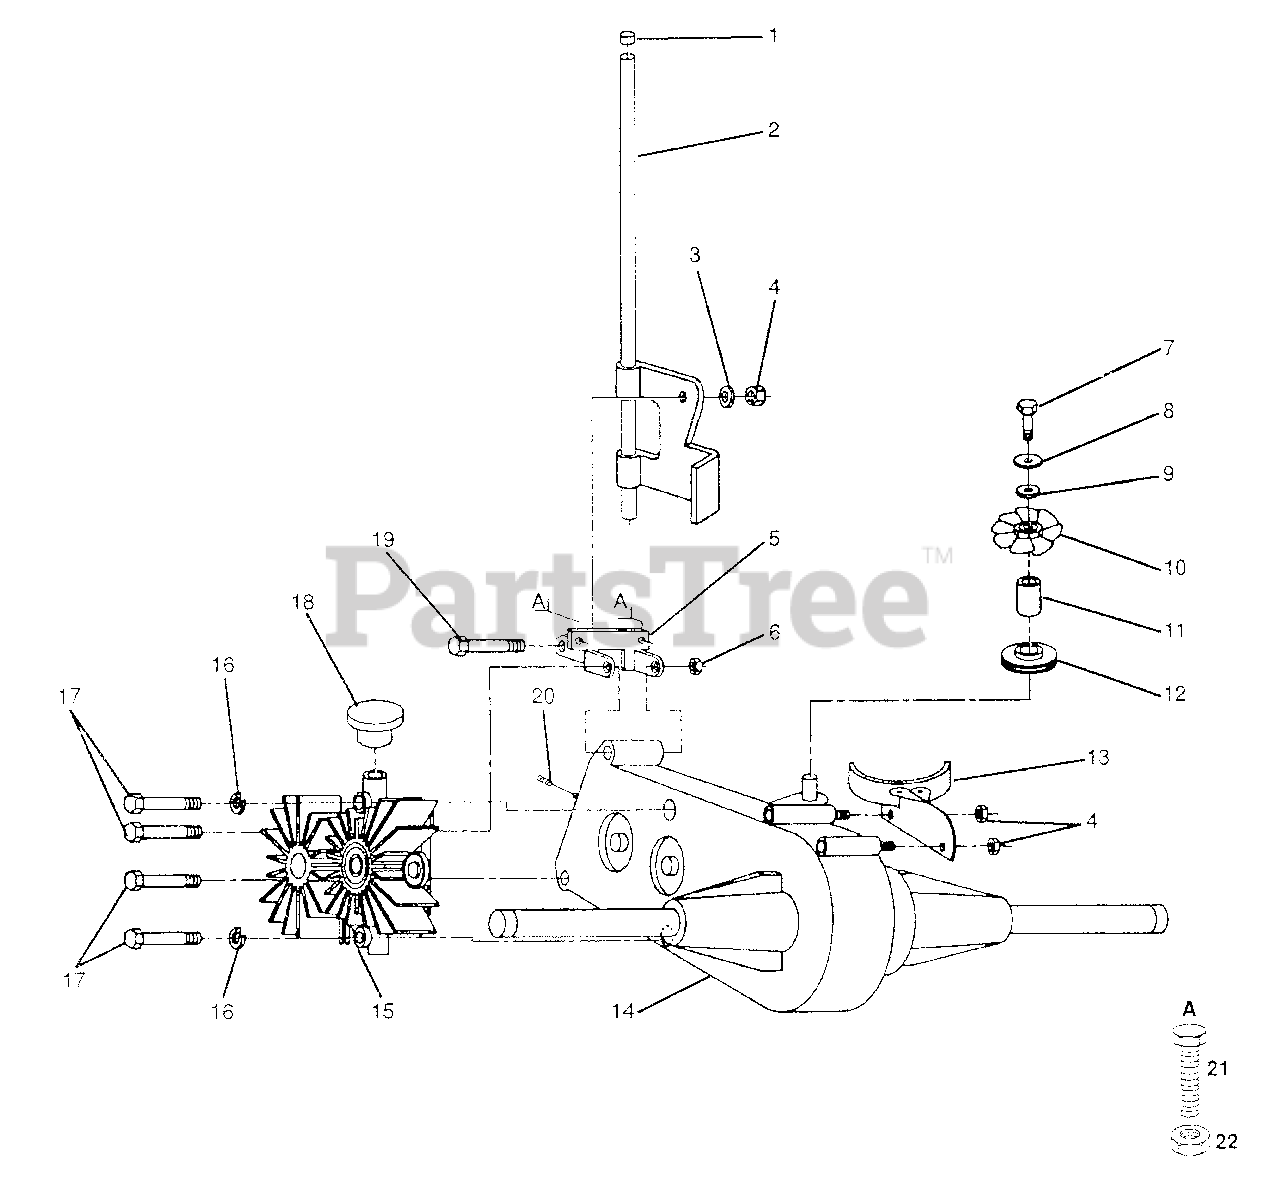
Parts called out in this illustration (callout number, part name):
1	Cap, Plunger
2	Rod, Free Wheel Control Assembly
3	Washer, Nylon
4	Nut, Crownlock 1/4 - 20 UNC
5	Bracket, Mounting Differential
6	Nut, Crownlock 5/16 - 18
7	Bolt, Hex 1/4 - 20 UNC x 3/4
8	Washer, Lock
9	Washer 9/32 x 1-1 /4 x 16 Gauge
10	Fan, Hydro 8"
11	Standoff, Fan, Hydro
12	Pulley, Transaxle
13	Guard Assembly, Belt
14	Differential Assembly
15	Pump Assembly
16	Washer, Lock
17	Bolt, Hex, Fin 5/16 - 18 UNC x 4.5
18	Reservoir, Pump
19	Bolt, Shoulder 1/4 - 20 UNC
20	Spring, Compression
21	Bolt 3/8 - 16 x 3/4
22	Nut, Crownlock 3/8 - 16 UNC
